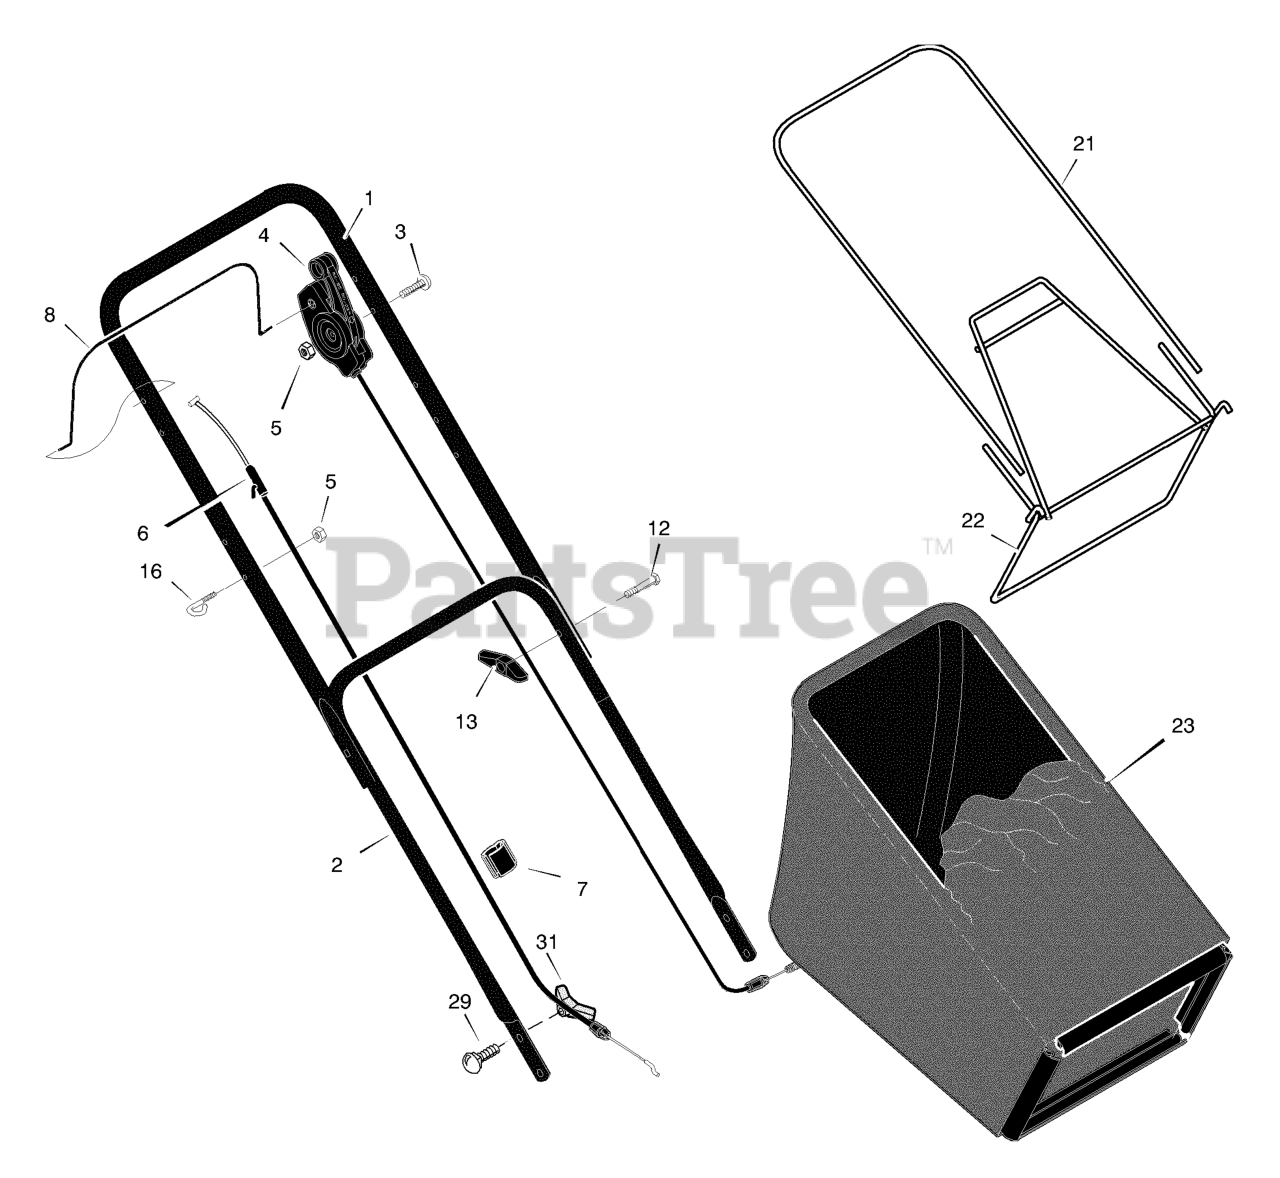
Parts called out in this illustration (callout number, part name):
1	Handle, Upper (Black)
2	Handle, Lower (Black)
4	Control, Drive
5	Locknut
6	Cable, Stop
7	Fastener, Cable
8	Lever, Stop
13	Knob
16	Guide, Rope
21	Frame, Top
22	Frame Assembly
23	Bag, Cloth
29	Bolt, Carriage
31	Knob, Plastic
